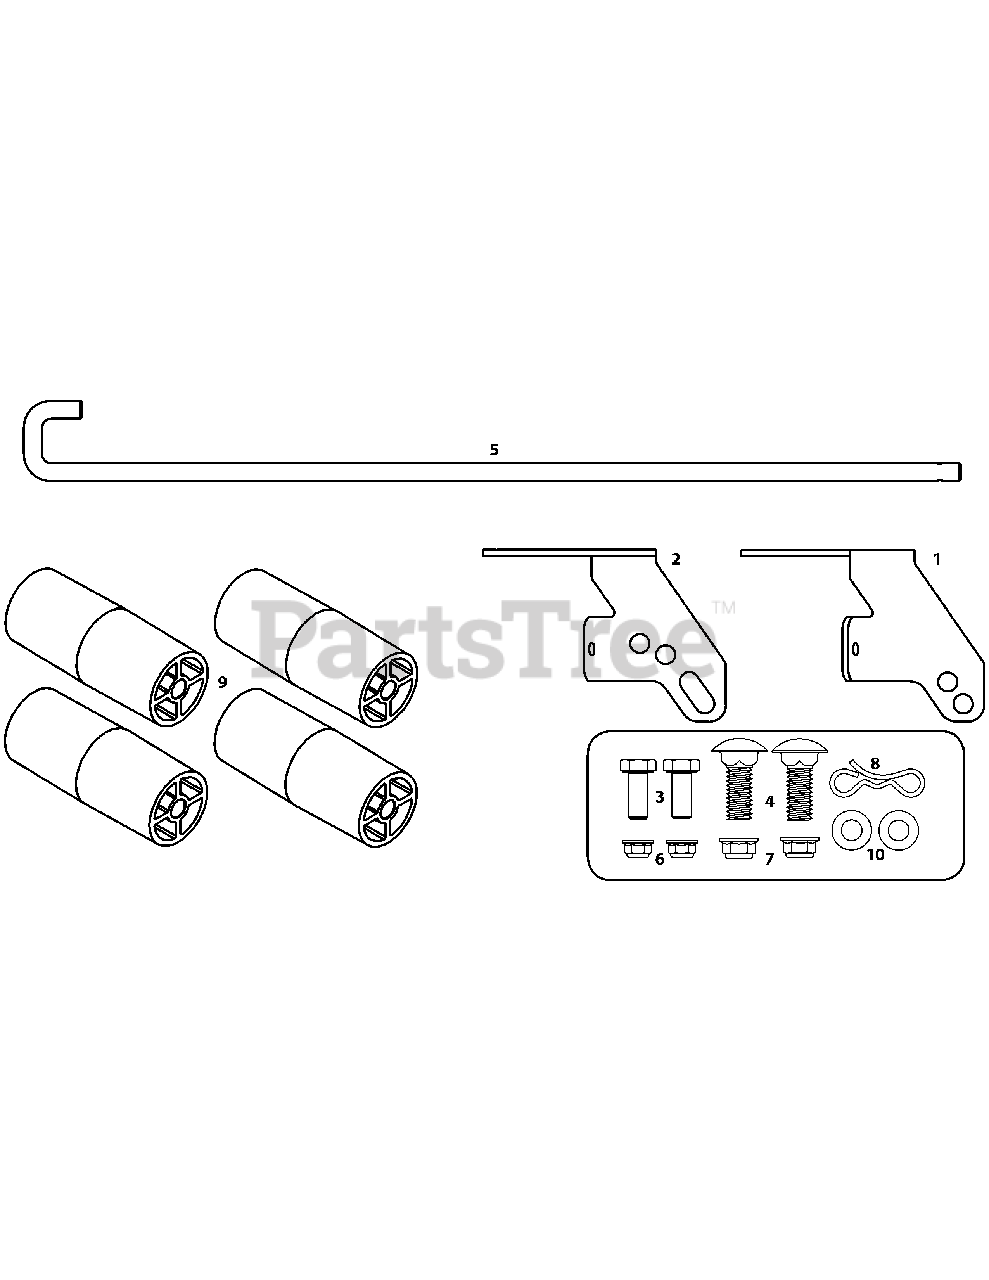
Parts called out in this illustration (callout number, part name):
1	Right Roller Bracket
2	Left Roller Bracket
3	Hex Screw, 5/16-18 x .75
4	Carriage Bolt, 3/8-16 x 1.00
5	Roller J-hook, 26"
6	Flange Lock Nut, 5/16-18
7	Flange Lock Nut, 3/8-16
8	Bow-tie Cotter Pin, 91
9	Front Roller
10	Flat Washer, .330 x .630 x .064
